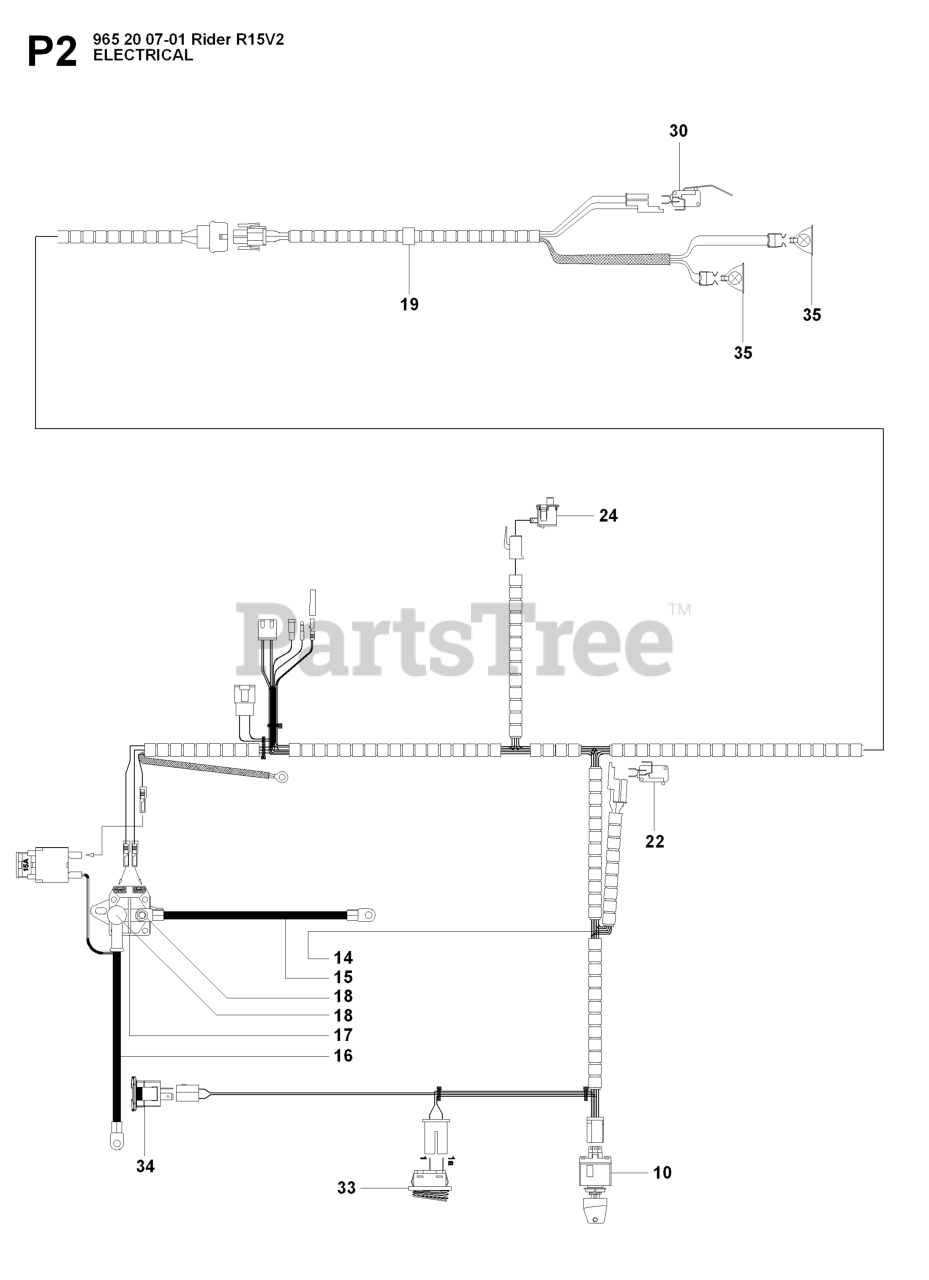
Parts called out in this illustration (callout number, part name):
10	IGNITION SWITCH
19	WIRING
22	%BRAKER
30	RP MICRO SWITCH
